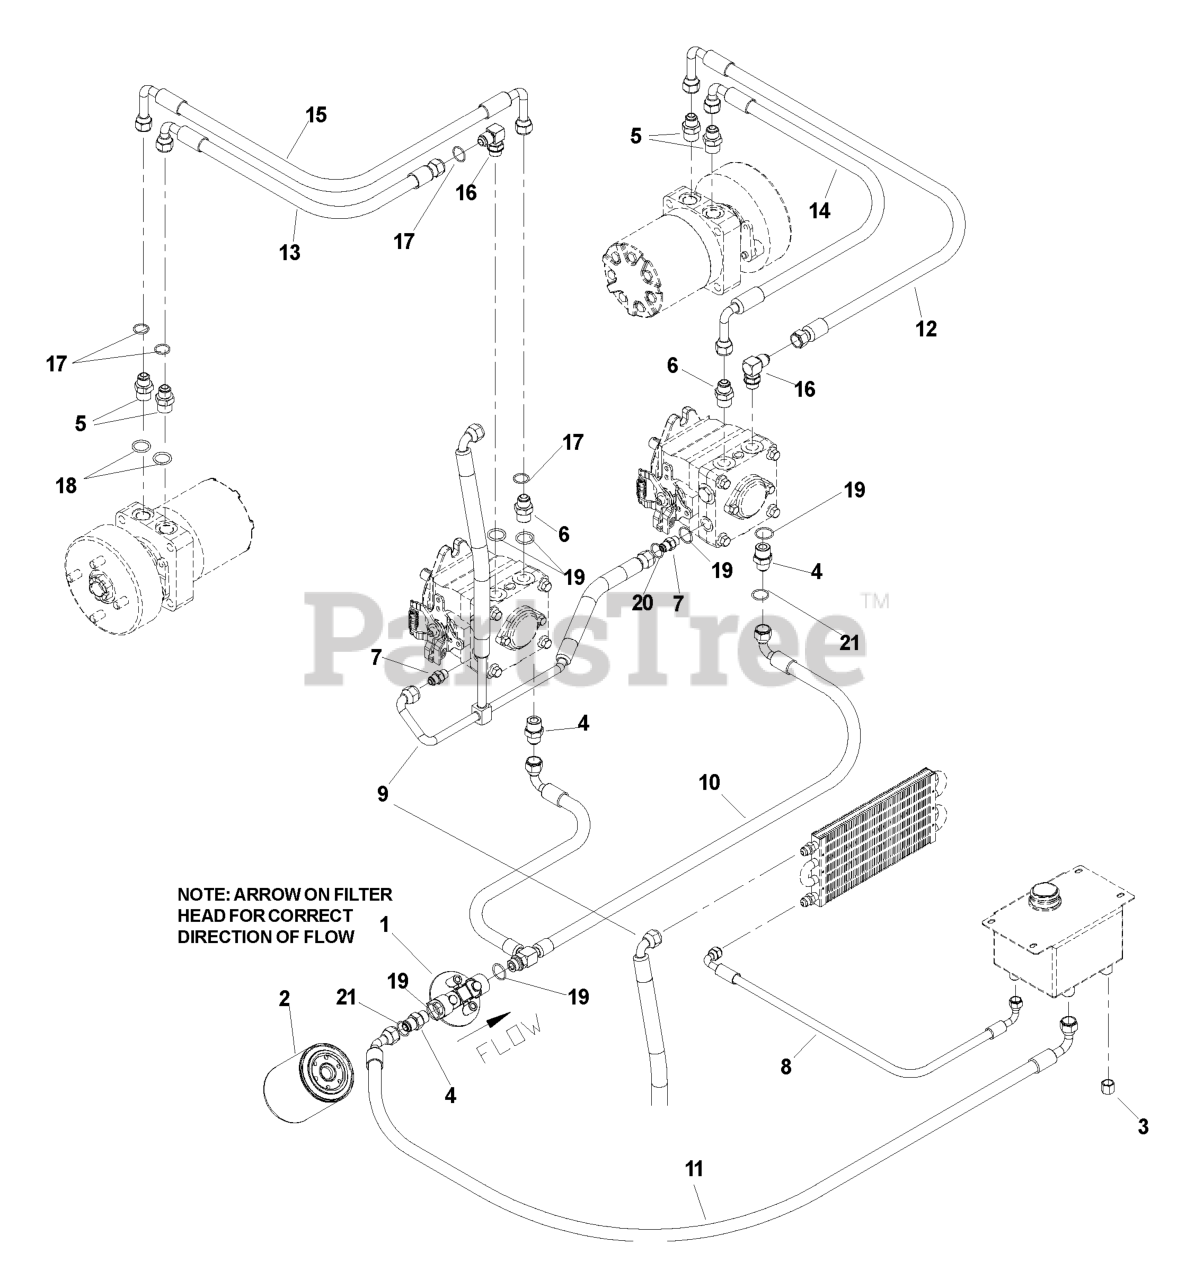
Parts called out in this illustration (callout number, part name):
1	FILTER HEAD
2	HYDRAULIC OIL FILTER
3	NUT 9/16-18 JIC CAP
4	FITTING, STRAIGHT F6400-8-8-0
